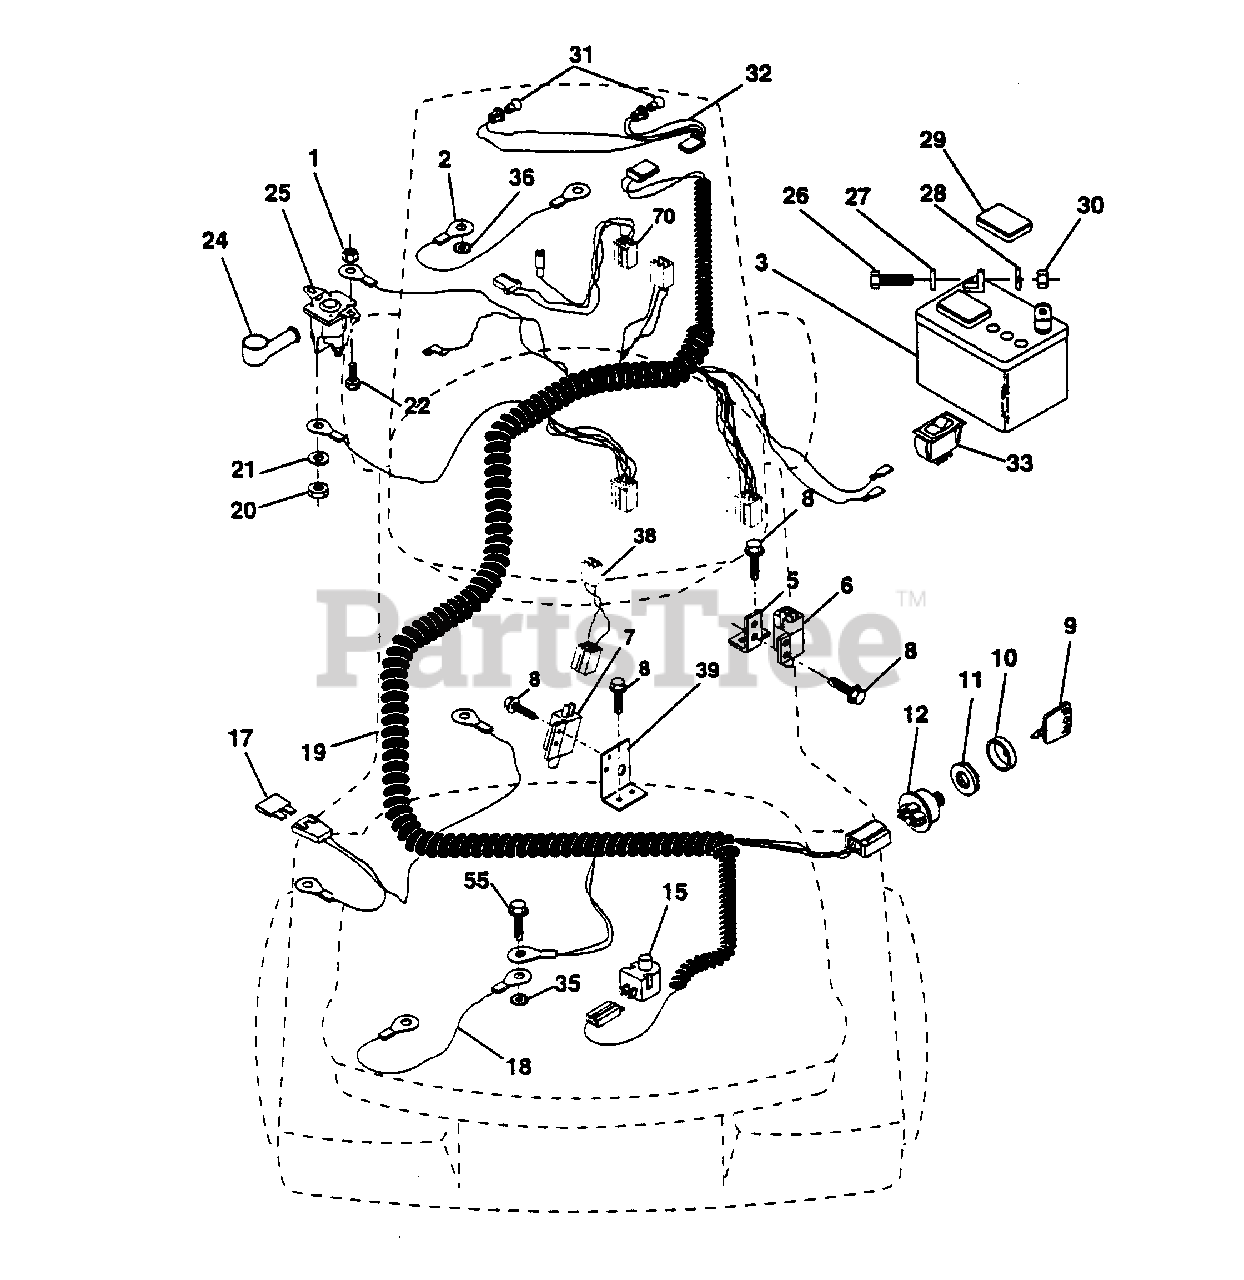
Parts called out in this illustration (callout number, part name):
1	Nut, Hex, Keps 1/4-20 (AYP part number)
2	Assembly, Cable (AYP part number)
3	Battery (AYP part number)
5	Bracket, Switch (AYP part number)
6	Switch, Interlock, 4 Terminal (AYP part number)
7	Switch, Interlock, 2 Terminal (AYP part number)
8	Screw, Hex Head, Self-Tapping #10-24 x 1/2 (AYP part number)
9	Key, Molded (AYP part number)
10	Cover, Ignition Key (AYP part number)
11	Nut, Ignition (AYP part number)
12	Switch, Ignition (AYP part number)
15	Switch, Plunger (AYP part number)
17	Fuse (AYP part number)
18	Assembly, Cable (AYP part number)
19	Harness, Ignition (AYP part number)
20	Nut, Hex, Jam 1/4-20 (AYP part number)
21	Washer, Lock 1/4 (AYP part number)
22	Bolt, Hex, Fin. 1/4-20 UNC x 1/2 Grade 5 (AYP part number)
24	Cover, Terminal (AYP part number)
25	Solenoid (AYP part number)
26	Bolt, Hex Head 1/4-20 UNC x 3/4 (AYP part number)
27	Washer 9/32 x 5/8 x 16 Gauge (AYP part number)
28	Washer, Lock 1/4 (AYP part number)
29	Cap, Battery (AYP part number)
30	Nut, Hex, Fin. 1/4-20 UNC (AYP part number)
31	Bulb, Light (AYP part number)
32	Harness, Headlight (AYP part number)
33	Switch, Light (AYP part number)
35	Washer, Lock, External Tooth 5/16 (AYP part number)
36	Washer, Lock, Internal Tooth 1/4 (AYP part number)
38	Harness Adapter (AYP part number)
39	Bracket, Switch Clutch (AYP part number)
55	Screw Thdrol 5/16-18 x 1/2 (AYP part number)
70	Harness Engine (AYP part number)
